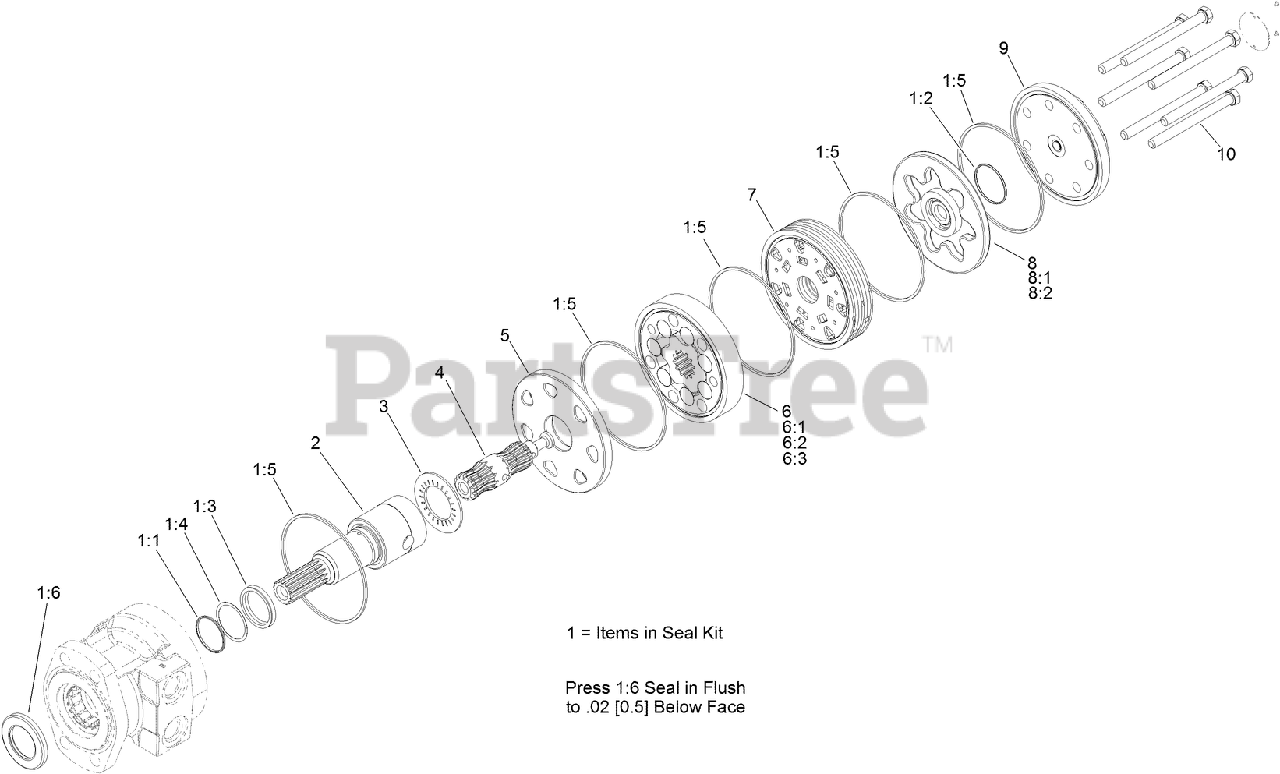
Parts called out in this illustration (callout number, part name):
1	SEAL KIT
1:1	HUB and BEARING ASM
1:2	HUB and BEARING ASM
1:3	SEAL-SHAFT
1:4	HUB and BEARING ASM
1:5	HUB and BEARING ASM
1:6	HUB and BEARING ASM
2	Shaft-Coupling
3	BEARING-THRUST
4	LINK-DRIVE
5	PLATE-WEAR
6	ROTOR SET
6:1	HUB and BEARING ASM
6:2	HUB and BEARING ASM
6:3	HUB and BEARING ASM
7	MANIFOLD
8	COMMUTATOR ASM
8:1	HUB and BEARING ASM
8:2	HUB and BEARING ASM
9	END COVER ASM
10	Bolt-Special
